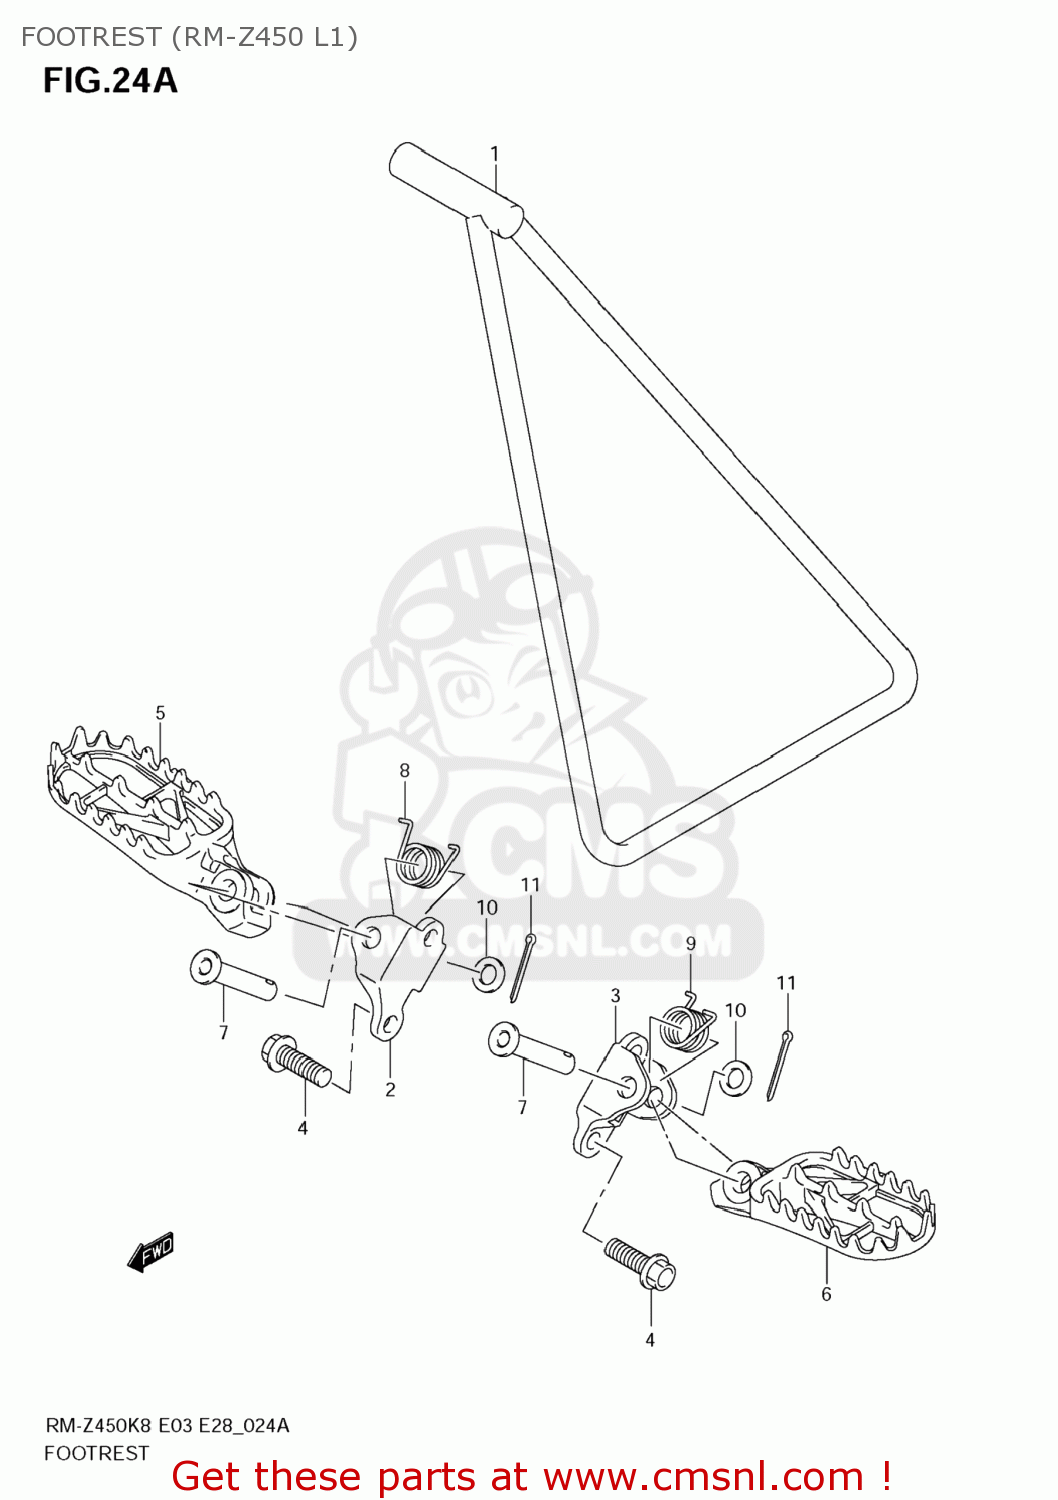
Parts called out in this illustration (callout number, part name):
1	STAND
2	BRACKET,FOOTREST,R
3	BRACKET,FOOTREST,L
4	BOLT(10X25)
5	FOOTREST,R
6	FOOTREST,L
7	PIN
8	SPRING
9	SPRING
10	WASHER
11	PIN
